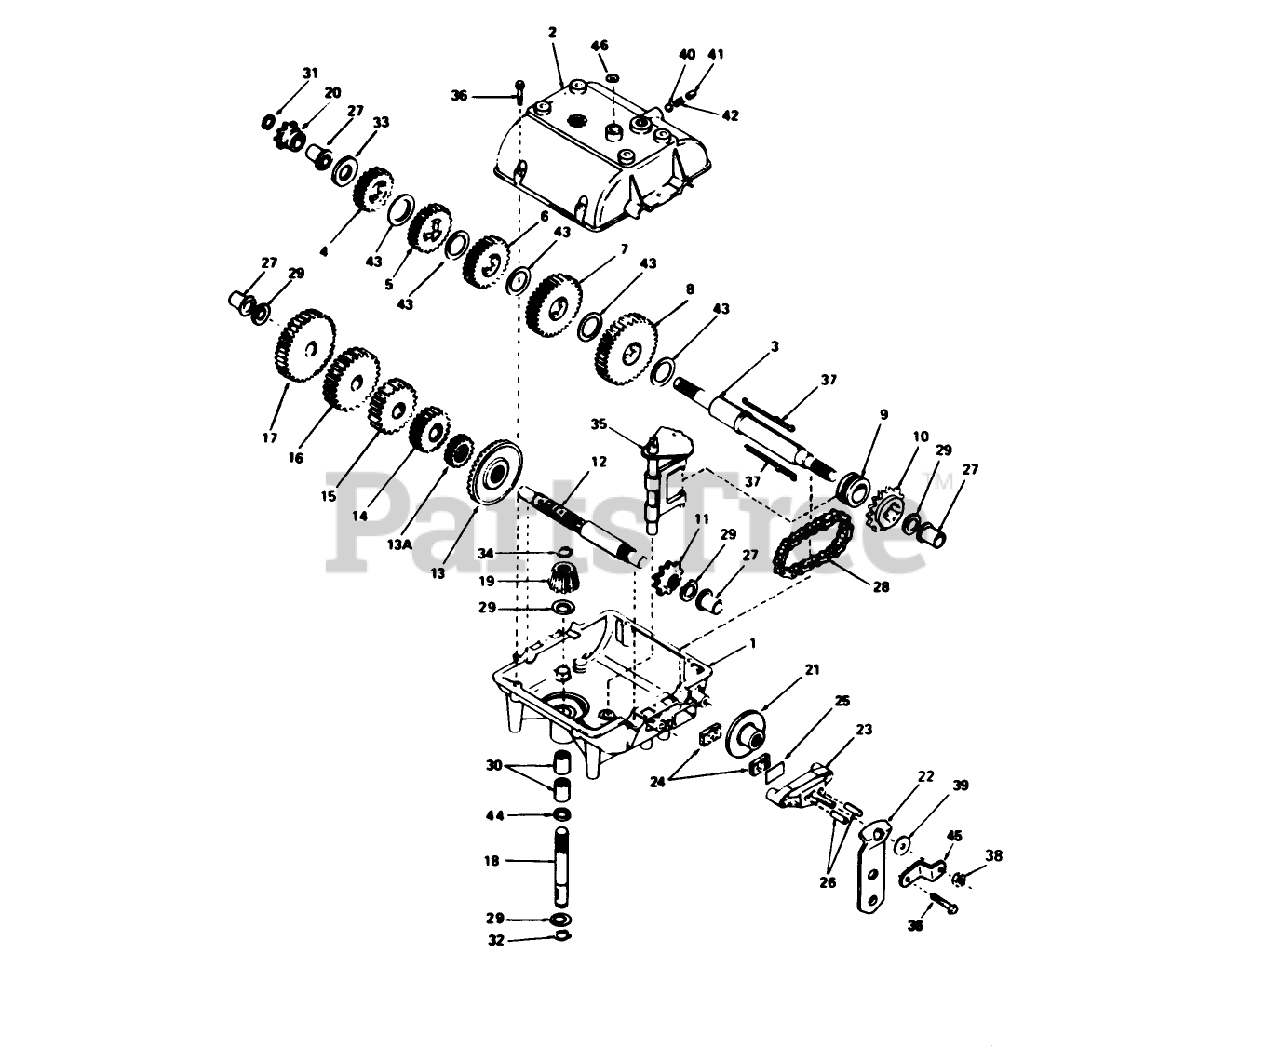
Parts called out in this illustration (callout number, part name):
1	Case-Transmission
2	Cover-Transmission
3	Shaft-Output Brake
4	Gear-Spur 20 teeth
5	Gear-Spur (22 teeth)
6	Gear-Spur, 25 Teeth
7	Gear-Spur, 30 Teeth
8	Gear-Spur, 35 Teeth
9	Collar-Shift
10	Sprocket-18 Teeth
11	Sprocket-9 Teeth
12	Countershaft
13	Gear-Bevel (42Teeth)
13A	Gear-Spur 15 Teeth
14	Gear-Spur, 20 Teeth
15	Gear-Spur, 25 Teeth
16	Gear-Spur (28 teeth)
17	Gear-Spur (30 teeth)
18	Shaft-Input
19	Bevel Pinion-Input
20	Sprocket (8 teeth)
22	Lever-Brake
23	Nozzle-Carburetor
24	Brake Pad
25	Brake Pad Plate
26	Dowel Pin
27	Bushing-Flange
28	Chain-Roller #41
29	Washer
30	Bearing-Needle
31	Piston Asm (.020 O S)
32	Ring-Snap
33	Washer
34	Ring-Retainer
35	Rod and Fork ASM
36	Ring Set (.020 O S)
38	Locknut
39	Washer
40	Ball-Steel
41	Screw-Set
42	Spring
43	Washer
44	O Ring
45	Bracket
46	Cut Seal-Square
